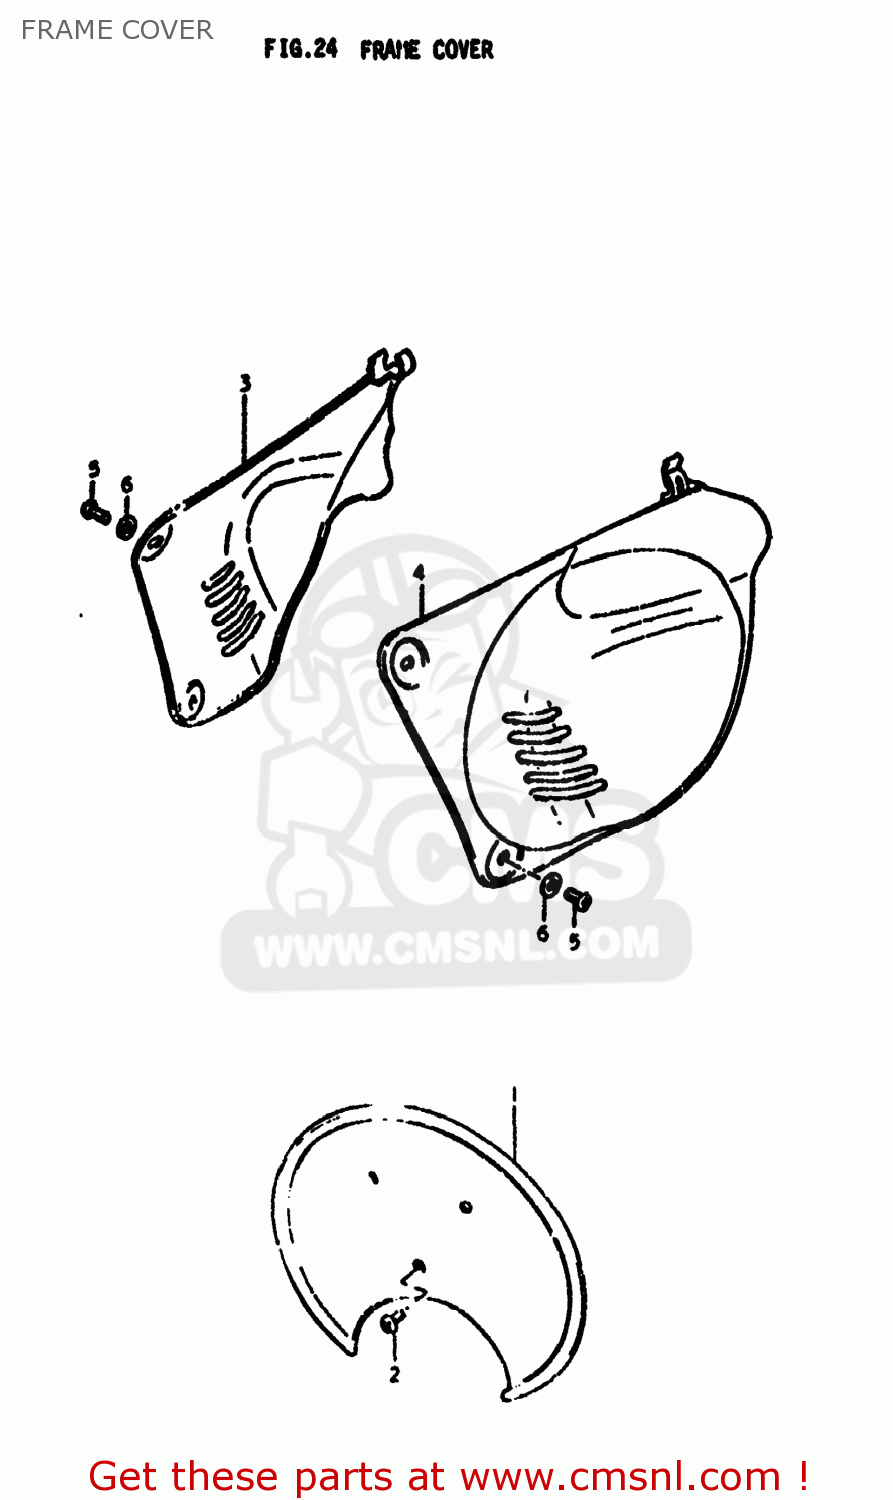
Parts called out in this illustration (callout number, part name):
1	PLATE,FRONT NUMBER
2	SCREW
3	COVER,FRAME,RIGHT
4	COVER,FRAME,LEFT
5	SCREW 6X12
6	SPACER
